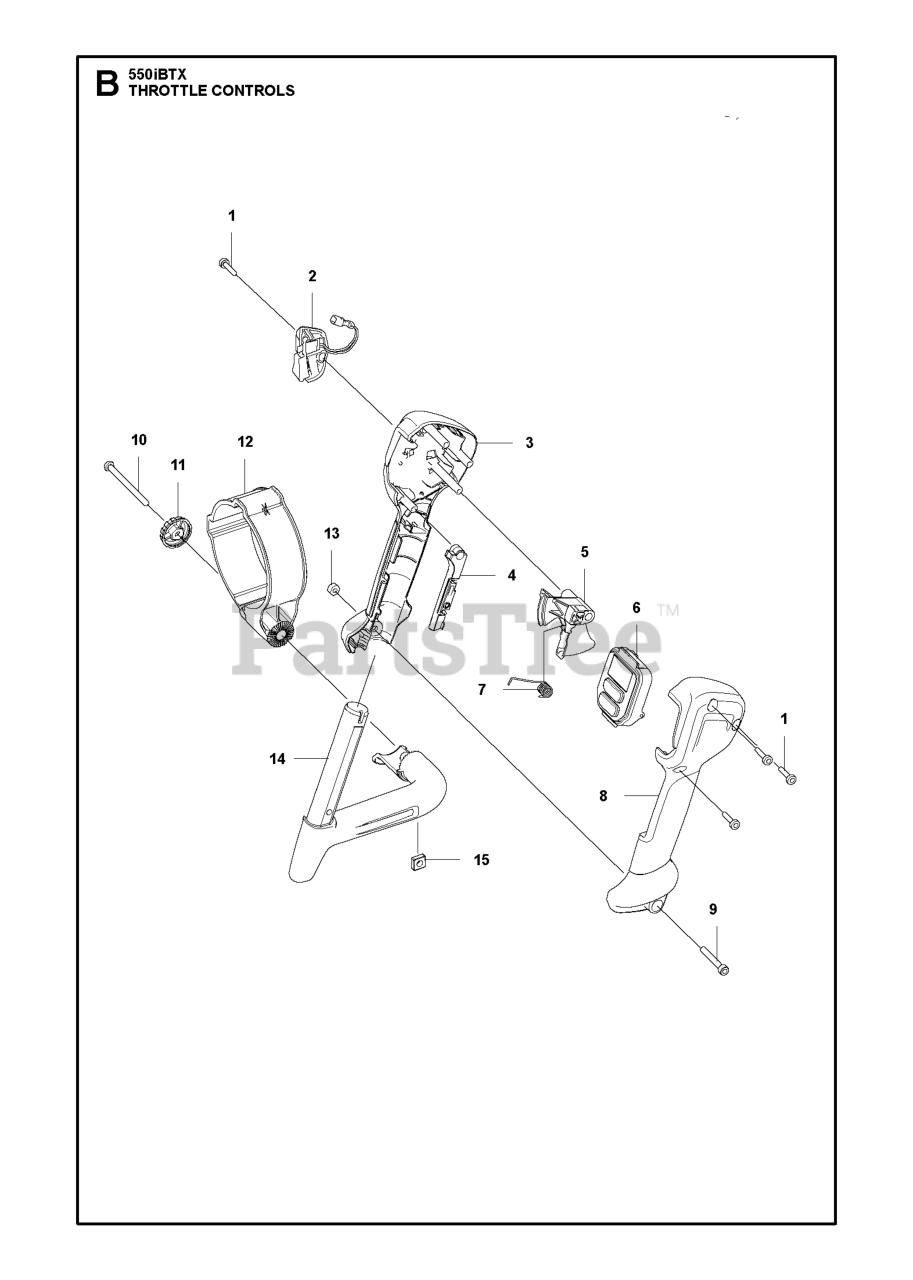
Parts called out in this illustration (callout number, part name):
1	SCREW ITXSCT PW4.2X18 10.9 ZN
2	BUTTON ASSY SIDE CRUISE
3	HANDLE HALF LEFT
4	COVER HANDLE ESD
5	THROTTLE CONTROL ASSY
7	SPRING THROTTLE CONTROL
8	HANDLE HALF RIGHT
12	HANDLE HOLDER
14	HOLDER HANDLE
